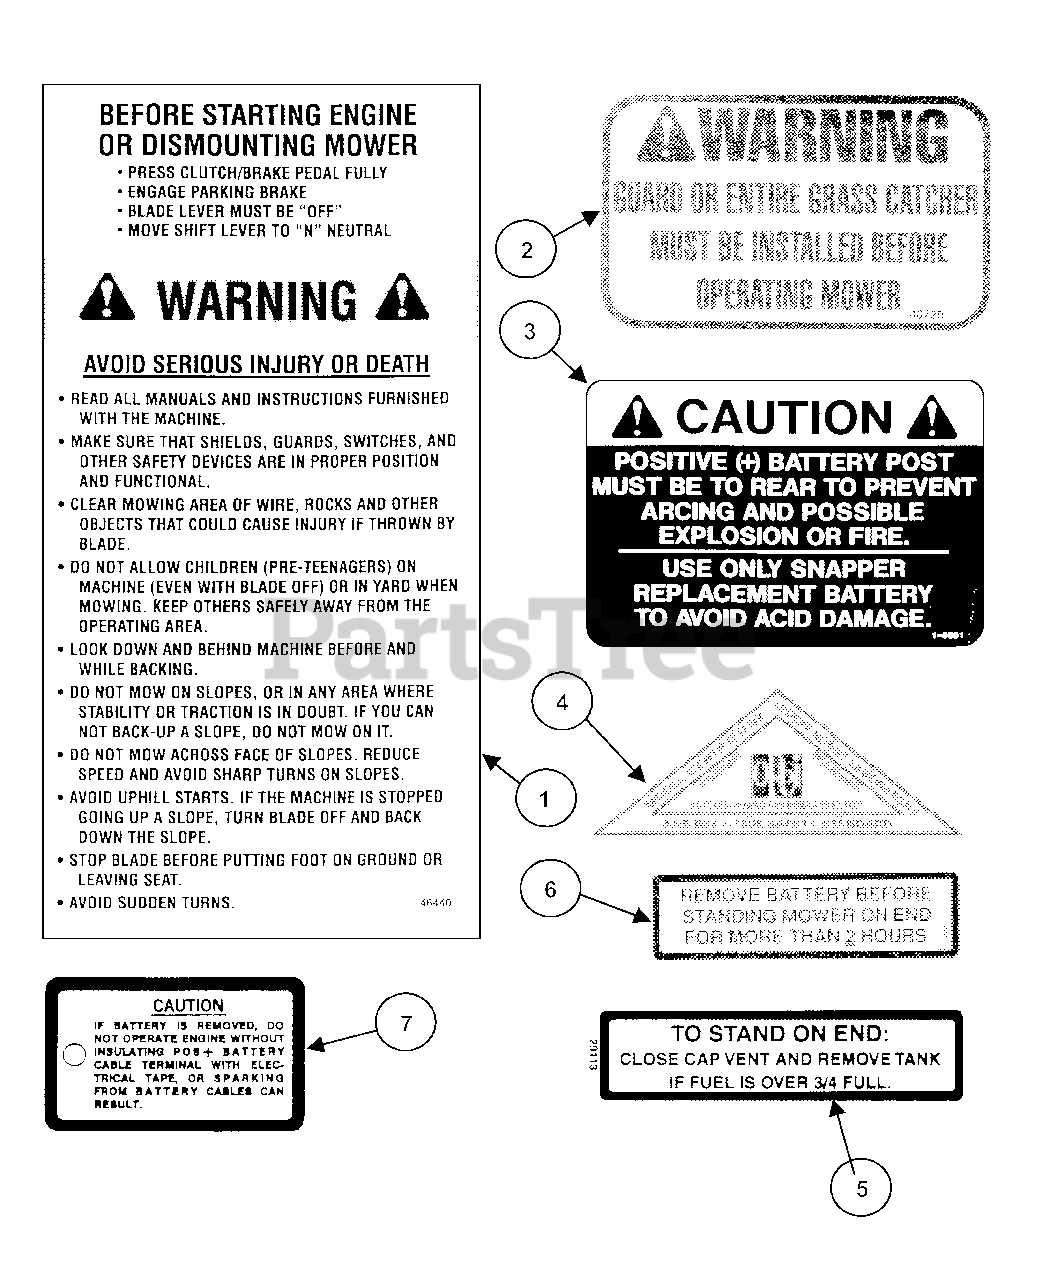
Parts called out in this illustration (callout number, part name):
1	DECAL, Safety Instructions
2	DECAL, Chute/Deflector Warning
3	DECAL, Battery Caution
4	DECAL, OPEI, Ride-On
5	DECAL, Caution, Fuel (English)
6	DECAL, Battery
7	DECAL, Caution Tag
